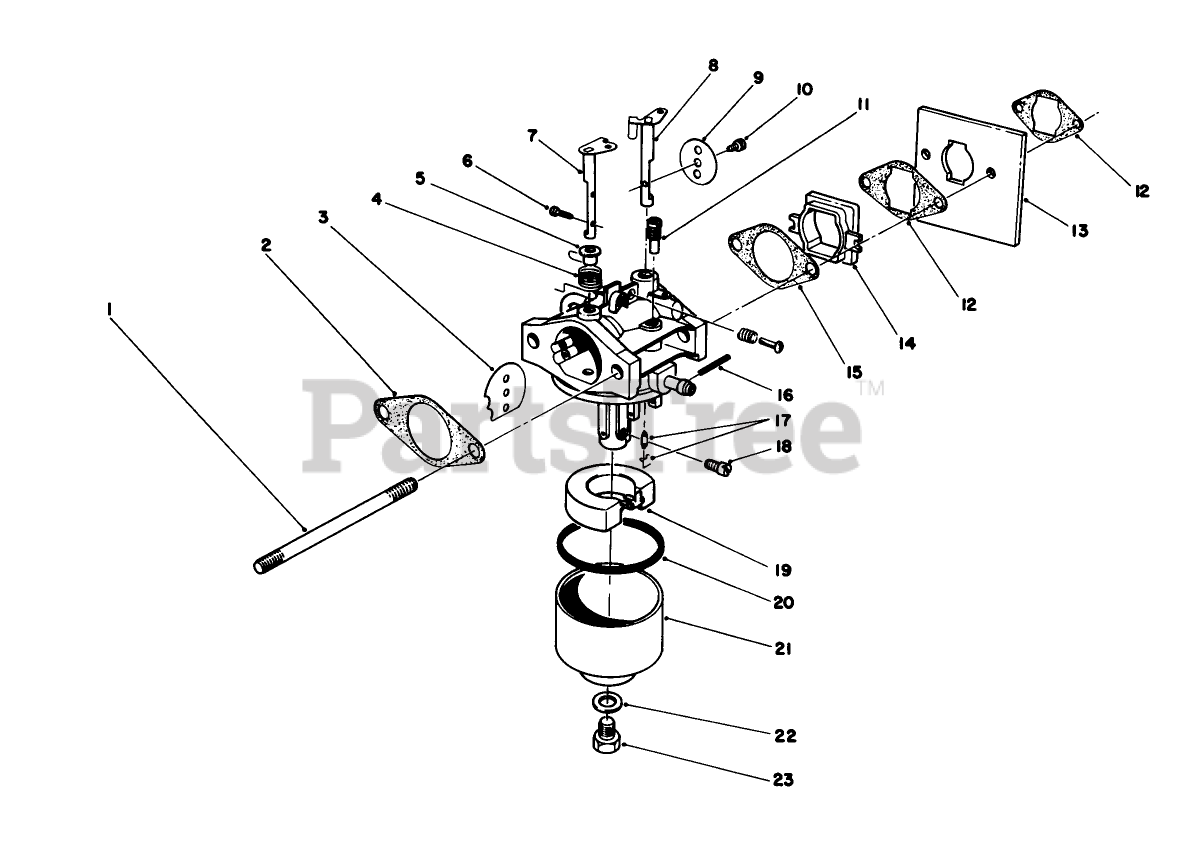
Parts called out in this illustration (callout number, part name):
1	CARB STUD BOLT
2	GASKET-AIR CLEANER
3	CHOKE VALVE
4	Spring-Choke
5	BUSHING
6	SCREW
7	SHAFT-CHOKE
8	SHAFT
9	PLATE
11	PILOT JET
12	GASKET-CARBURETOR
14	INSULATOR
15	GASKET-CARB
17	NEEDLE
19	FLOAT
20	GASKET
22	GASKET
